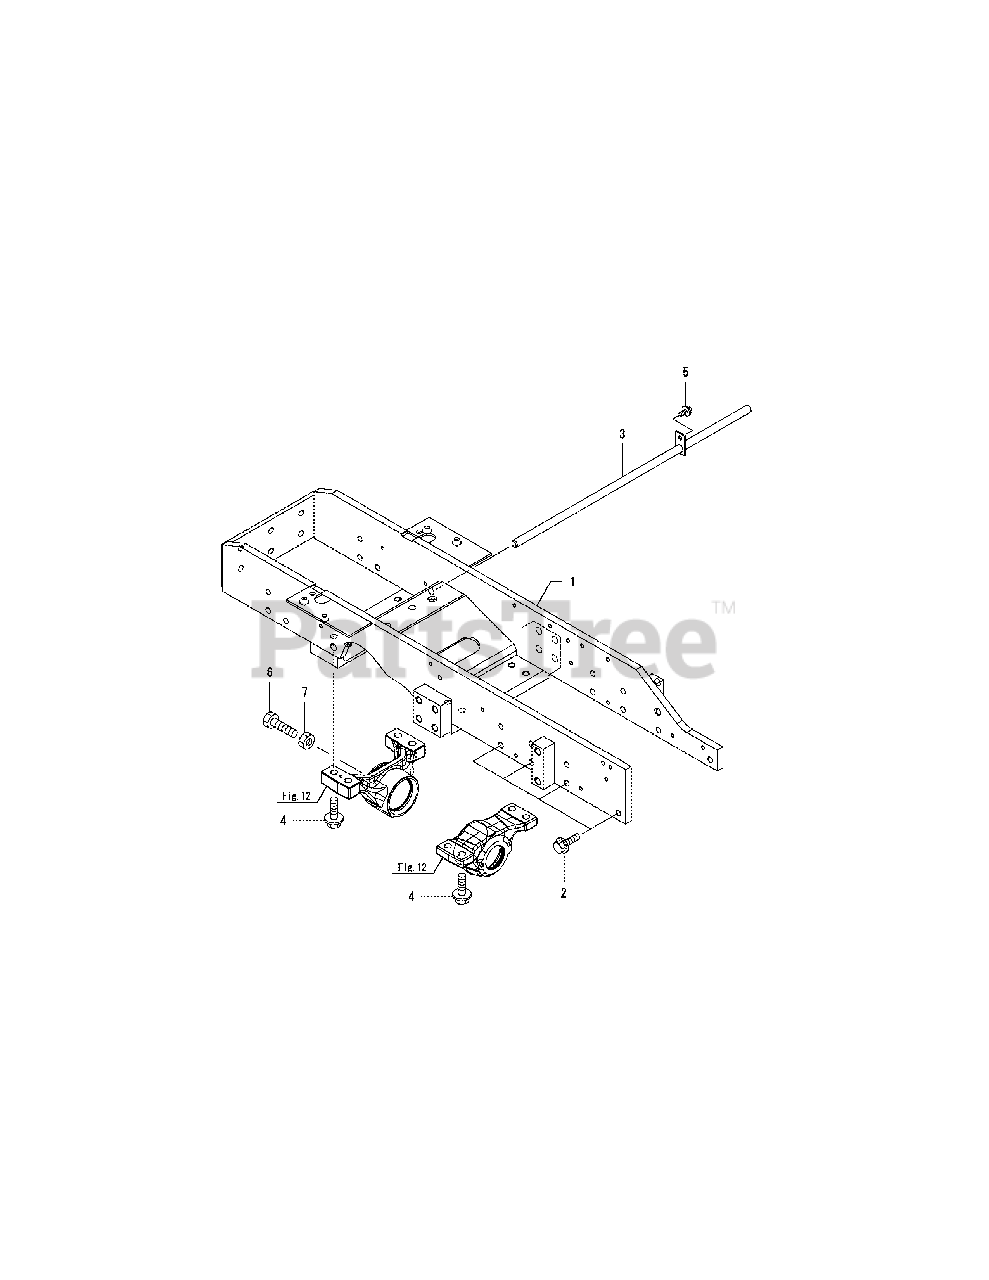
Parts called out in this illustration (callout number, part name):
1	BRACKET ASSY, F AXLE
3	GUARD, PST CYLINDER
5	BOLT M 8X 16 PLATED
6	BOLT M16X 60 PLATED
